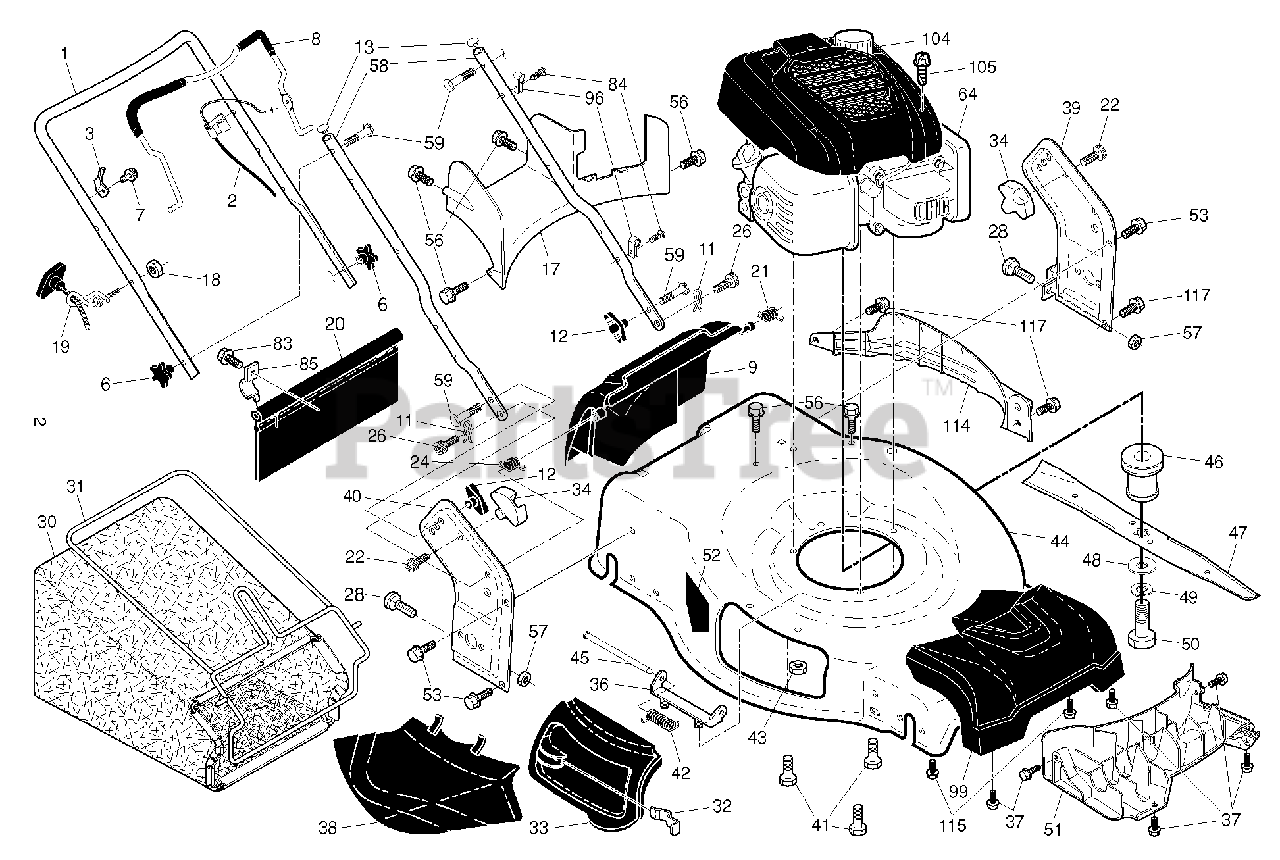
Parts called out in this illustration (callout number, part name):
1	HANDLE.UPPER.3.POS.BS.AW2.GREY
2	CABLE.MZR.50.SNAP-IN
3	BRACKET.UPSTOP.RT
6	KNOB.HANDLE.PLASTIC.STAR.BLACK
8	BAIL.OVER.MOLD.ERGO.MZR.ORANGE
9	DOOR.REAR.ASM.22+.HUSQ.FG/RGD
11	COTTER.HAIRPIN.DOOR/HANDLE.PIV
12	KNOB, DEFLECTOR
13	PLUG.PLASTIC.7/8".14-20.GAUGE
17	BAFFLE.REAR.22+RGD.AWD.PLASTIC
18	NUT
19	RB GUIDE.ROPE.STD.BLK.ZIN WSL
20	SKIRT.REAR.22PLUS.RGD.LW(2 2MC
21	SPRING.LH.BLACK
22	SCREW.PAN.HEAD.#10
24	SPRING.RH.GRAY
26	SCREW,DOOR/HANDLE.PIVOT
28	BOLT
30	GBAG.BA85028EM.NOFRAME.GRY/SLV
31	RB FRAME.GBAG.22PLUS
32	LATCH.DOOR.ZINC
33	DOOR.MULCH.22 PLUS.HUSQ.GREY
34	BRACKET.GRASSBAG.ATTACHING.BLK
36	BRACKET.ASM.HINGE.21.FWGD.
37	SCREW.HI-LO.5/16 X.75
38	DEFLECTOR.CLIPPING.22.BLACK
39	BRACKET.ASM.HNDL.LT.22+.GREY
40	BRACKET.ASM.HNDL.RT.22+.GREY
41	BOLT 3/8-16X1-1/8
42	SPRING.TORSION
43	NUT.HEX.FLANGE.1/4
44	HOUSING.22+.AWD.MC.WO.ORANGE.T
45	ROD.HINGE.21
46	ADAPTER.BLADE.25MM.3MPH
47	BLADE.22+4N1.2PIN.5STAR.(P07)
48	WASHER,HARDEN
49	LOCKWASHER
50	SCREW, HEX HD 3/8-24 X 1-3/8
51	BAFFLE.FRONT.22+PLASTIC.(2 2)
52	DANGER DECAL
53	BOLT.5/16HEX.WHS.HD
56	SCREW.HX.13X.750
57	NUT.FLANGE.5/16
58	HANDLE.LOWER.22+BT.2PC.GRY
59	BOLT, HANDLE 5/16-18X1.75
83	TAPPING SCREW
84	FASTENER.PUSH.O.250X0.783
85	BRACKET.SKIRT.22+.BZP
96	CLIP.CABLE.BLK
99	COVER.ASM.FRONT.SHROUD.HUS.AWD
104	SHROUD.ASM.HONDA.HUSQVARNA
105	SCREW.SHROUD.HONDA
114	RP BUMPER.HUSQVARNA
115	SCREW.SHOULDER.5/16X1.375
117	BOLT.HEX.HD.WASHER.5/16-18X.75
